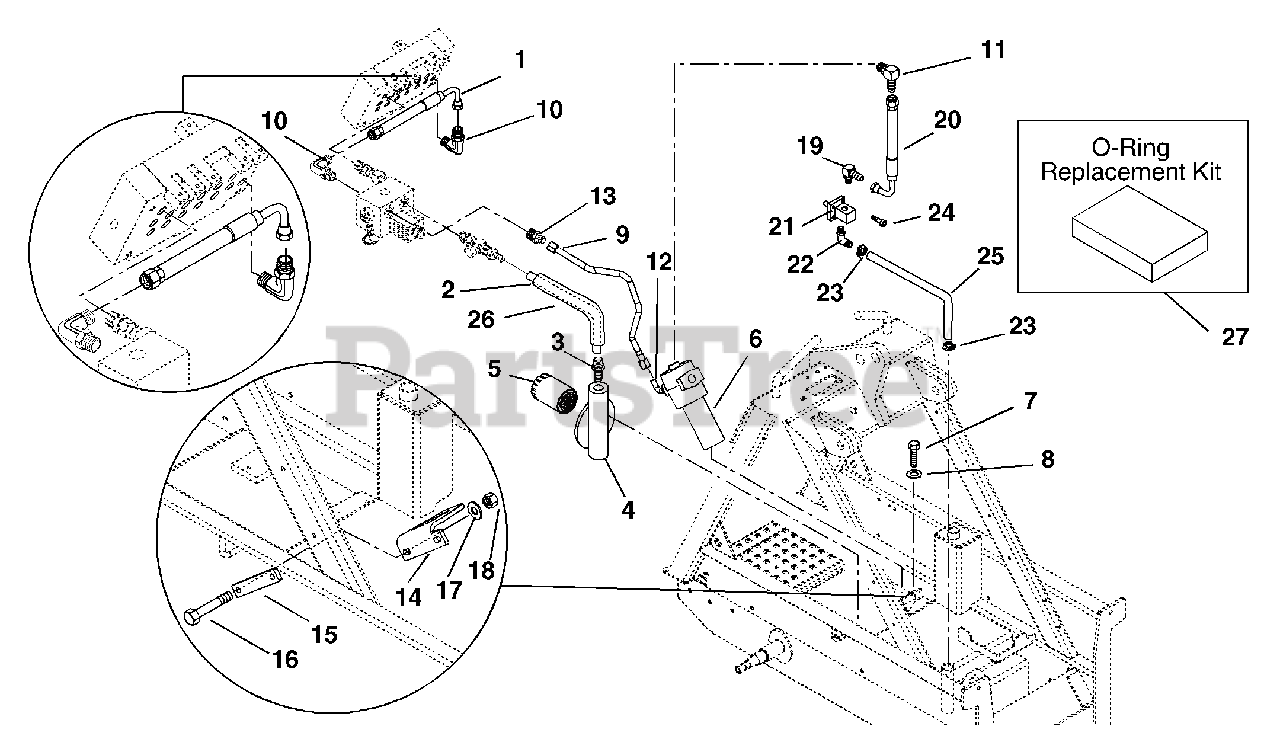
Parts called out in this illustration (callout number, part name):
1	Hose, Hydraulic .50-13-3K
2	Hose, Return Tee To Filter
3	Fitting, Male NPTF 10
4	Head-Filter
5	Filter-Hydraulic Skidster
6	Filter-Hydraulic Assembly
6	Filter-Element
7	Bolt-Hex .38-16 x 1.00 Grade 5
8	Washer-Flat-Steel .390 x .75 x .125
9	Tube, Filter To Overcenter Valve
10	Fitting, Hydraulic Elbow
11	Fitting, Hydraulic Elbow
12	Fitting, Hydraulic Elbow
13	Adapter, Face Sear 8 x 8 1/2 O-Ring
14	Bracket, Filter
15	Retainer, Filter Bracket
16	Bolt-Hex M8-1.25 x 65
17	Washer-Flat-Steel .38 x .875 xs .083
18	Nut-Locking-Nylon M8-1.25
19	Fitting, Hydraulic Elbow
20	Hose, Hydraulic Pump To Filter
21	Seals, Pump
22	Elbow-90 Degree
23	Clamp-Hose
24	Screw-Socket M8-1.25 x 30
25	Hose-Hydraulic Tank to Pump
26	Sleeve, Protective Hose
27	(Assorted O-Rings for Hydraulic Components to fittings) SAE
27	(Assorted O-Rings for Flat Face Seal Fittings and Hoses)
